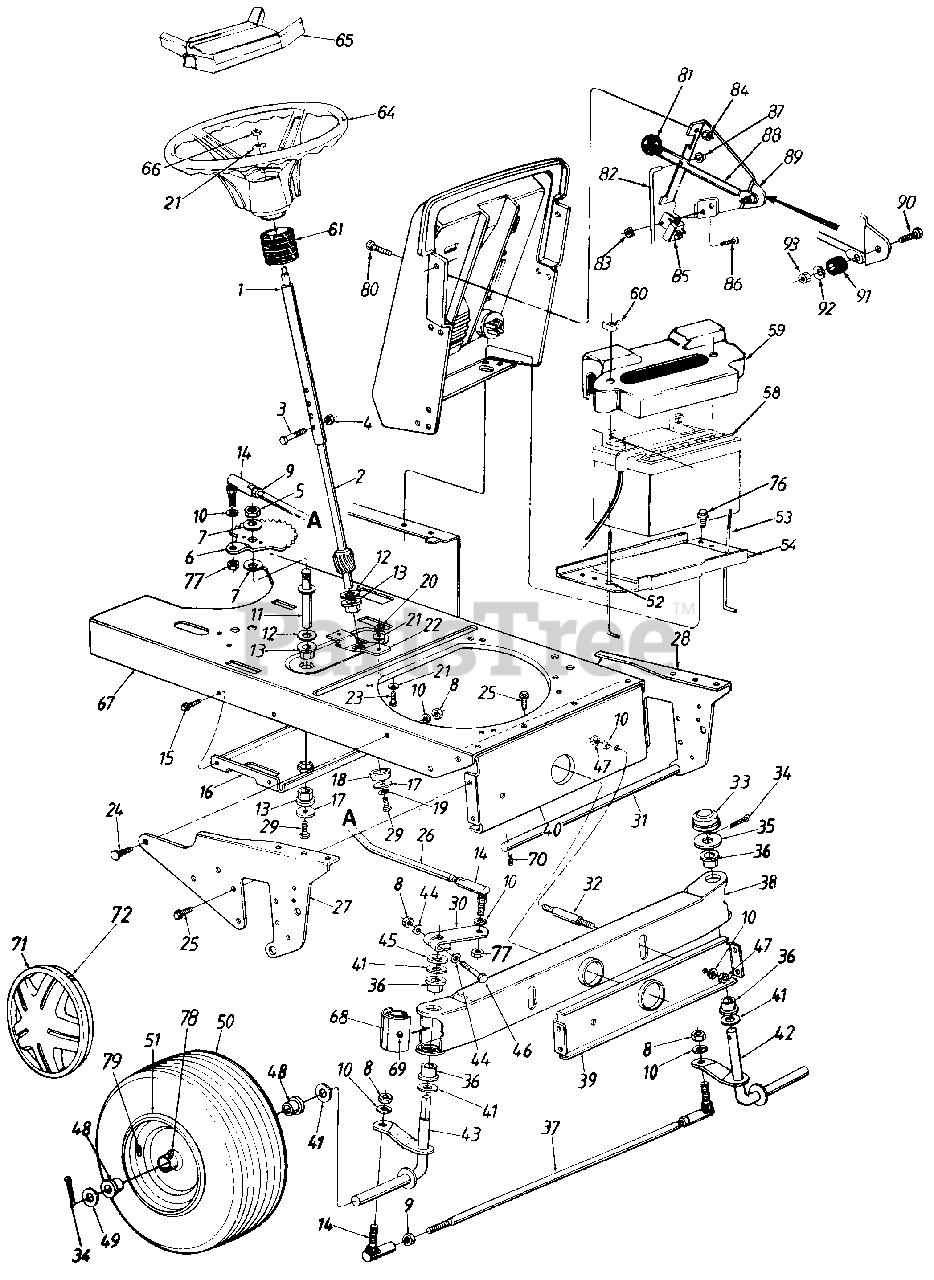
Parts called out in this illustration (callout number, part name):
1	Steering Column Ass'y.
2	Lower Steering Shaft
3	Hex Bolt 1/4-20 x 1.31" Lg.
4	Hex L-Nut 1/4-20 Thd.
5	Hex Nut 5/8-18 Thd.
6	Steering Gear Segment
7	Bell-Wash. 5/8" I.D. x 1.25" O.D.
8	Hex Nut 3/8-24 Thd.
9	Hex Jam NUt 3/8-24 Thd.
10	L-Wash. 3/8" I.D.
11	Steering Gear Segment Shaft
12	Fl-Wash. .64" I.D. x 1.24" O.D.
13	Hex Flange Brg. .63" I.D.
14	Ball Joint Ass'y
15	Hex Wash. Hd. TT-Tap Scr. 1/4-20 x 5." Lg.
17	Fl-Wash. .33" I.D. x 1.25" O.D.
18	Spacer .985" I.D. x 1.25" O.D.
19	L-Wash. 5/16" I.D.
20	Hex Nut 5/16-24 Thd.
21	Bell-Wash. .345" I.D. x .88" O.D.
24	Ribbed Neck Bolt 3/8-24 x .8" Lg.
25	Hex Wash. TT-Tap Scr. 5/16-18 x .62" Lg.
26	Steering Drag Link
30	Steering Arm Ass'y.
31	Deck Connecting Rod
32	Pivot Bar Shld. Bolt 3/8-16 x 5/8" Lg.
33	Cap
34	Cotter Pin 5/32" Dia.
35	Flat Washer
36	Flange Brg. .757" I.D.
37	Tie Rod 20.25" Lg.
38	Pivot Bar Assy.
41	Fl-Wash. .76" I.D. x 1.49" O.D.
42	Front Axle Ass'y. - L.H.
43	Front Axle Ass'y. - R.H.
44	Bowed Washer
45	Spacer .755" I.D. x 1.25" O.D.
46	Hex Bolt 3/8-24 x 2.25" Lg.
47	Hex Nut 3/8-16 Thd.
48	Flange Brg. .75" I.D.
49	Fl-Wash. .71" I.D. x 1.5" O.D.
53	Battery Hold Down Rod
54	Battery Plate
58	Battery
59	Battery Cover
60	Wing Nut Plastic 1/4-20 Thd.
61	Steering Bellow
64	Steering Wheel
65	Steering Wheel Insert
66	Hex L-Nut 5/16-24 Thd.
69	Grease Fitting
70	Internal Cotter Pin
71	Hub Cap
72	Spring Clip
76	Hex AB-Tap Scr. 1/4 x .62" Lg.
77	Hex Jam L-Nut 3/8-24 Thd.
78	Grease Fitting
79	Air Valve
80	Truss Mach. Scr. 1/4-20 x .5" Lg.
81	Shift Knob
82	Deck Control Rod
83	Hex Sems Nut #10-24 Thd.
84	Hex Sems Nut 1/4-20 Thd.
85	Safety Switch
86	Truss Mach. Scr. #10-24 x .5"
87	Push Nut
88	Blade Clutch Lever
89	Deck Clutch Control Brkt.
90	Hex Bolt 1/4-20 x 1.25" Lg.
91	Rubber Washer
92	Fl-Wash. .281" I.D. x .73"
93	Hex L-Nut 1/4-20 Thd.
